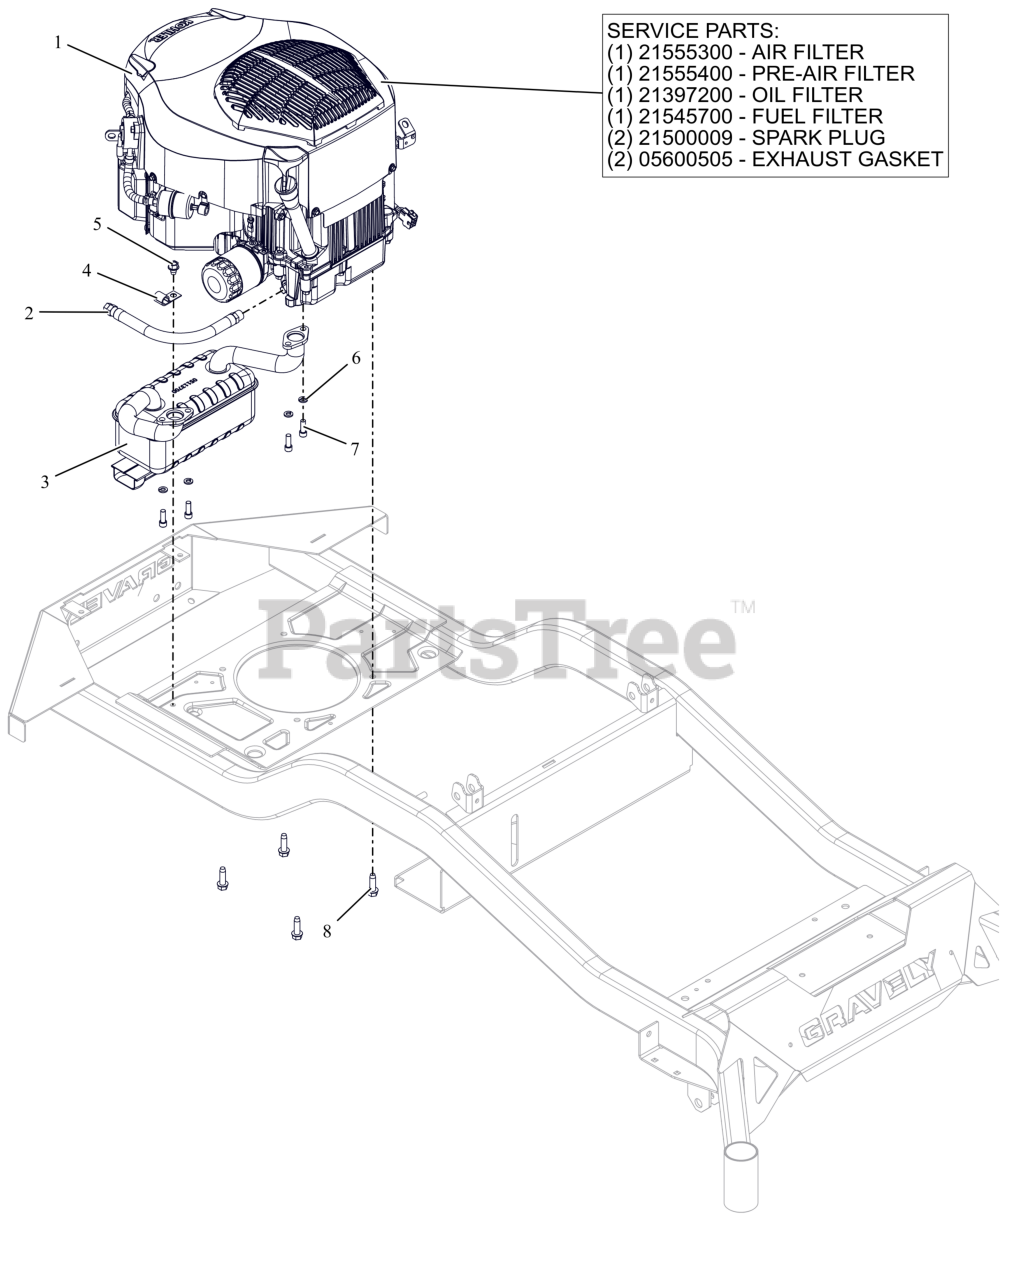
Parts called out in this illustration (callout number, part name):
1	ENGINE, KOHLER - KT740
1	AIR FILTER, KOHLER
1	PRE CLEANER, KOHLER
1	FILTER, OIL - KOH CV20
1	FILTER-FUEL KOHLER COURAGE PRO
1	PLUG, SPARK KOHLER
1	GASKET, MUFFLER KOHLER TWIN
2	HOSE, OIL DRAIN
3	MUFFLER, KOHLER
5	SCR,TAP .375-16X.50 HWH TR ZCC
6	WSHR,LK-REG .312X.078 ZCC
7	SCR, SKH .312-18X.875 GR8 ZCC
8	SCR,TAP .375-16X1.25HWH TR ZCC
